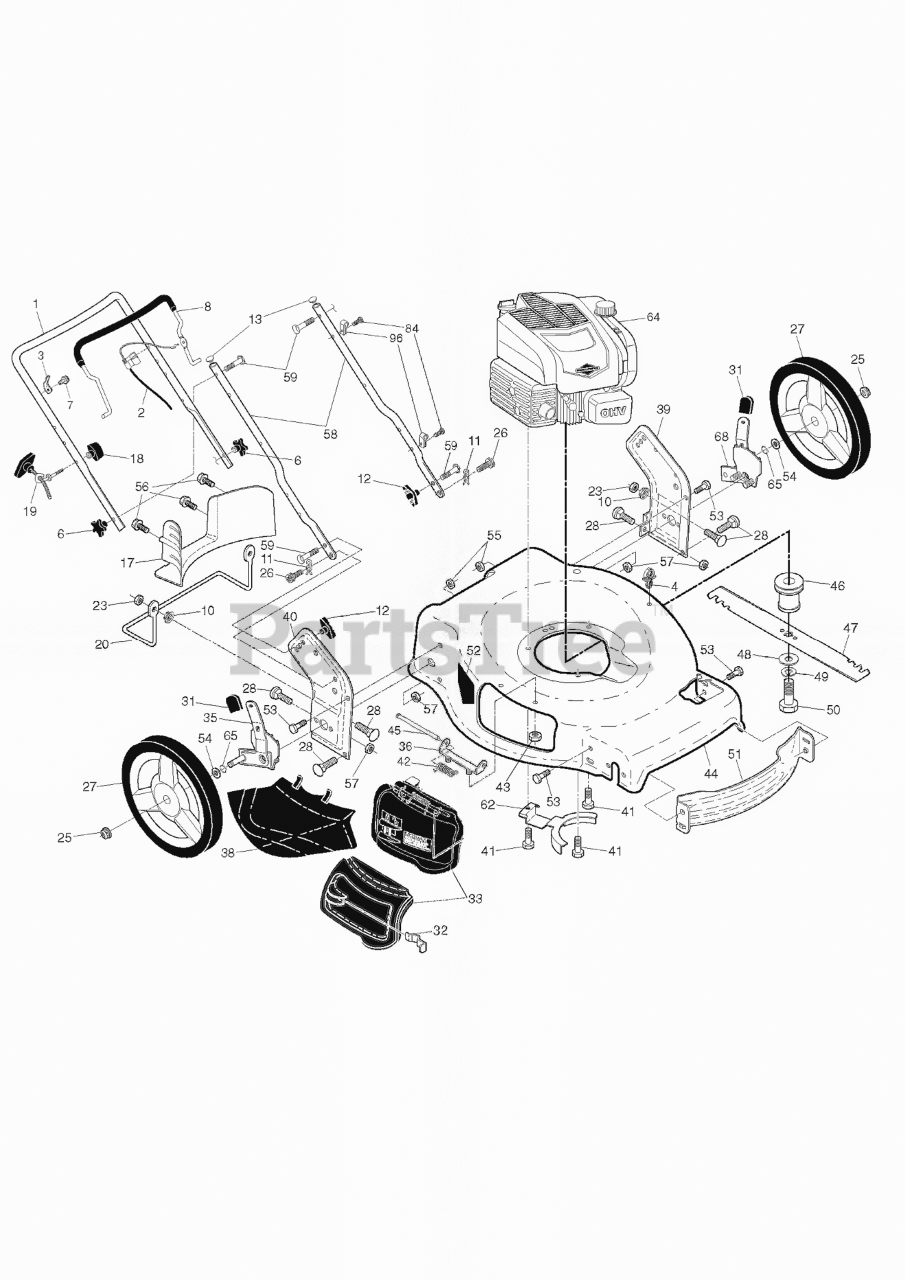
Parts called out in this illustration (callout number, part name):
1	HANDLE.UP.CURV.PUSH.498
2	CABLE.MZR.FGD.PLUS
2	CABLE.MZR.FGD.22+.ERGO
3	BRACKET.UPSTOP.RT
6	KNOB.HANDLE.PLASTIC.STAR.BLACK
7	SCREW
8	BAIL.OVER.MOLD.ERGO.MZR.ORANGE
8	BAIL.OM.ERGO.BENT.MZR.ORAN.668
10	WASHER 5/16"
11	COTTER.HAIRPIN.DOOR/HANDLE.PIV
12	KNOB, DEFLECTOR
13	PLUG.PLASTIC.7/8".14-20.GAUGE
17	BAFFLE.22PLUS.FGD.REAR.
18	T-KNOB.NEW ROPE GUIDE
19	GUIDE.ROPE.BLK.ZINC.CHROM
20	FOOTGUARD.REAR.22PLUS.BLK
23	LOCKNUT-FLANGE 5/16-18
25	NUT.HEX.FLANGE.3/8-16.LOCKNUT
26	SCREW,DOOR/HANDLE.PIVOT
27	WHEEL.12X1.75.CF H3SPK.RAD3.BB
28	BOLT
28	BOLT.CARRIAGE.LN.5/16-18X.5/8
31	SELECTOR KNOB
32	LATCH.DOOR.ZINC
33	DOOR ASSY KIT.MULCH DOOR.CE 22
33	DOOR.MULCH.22 PLUS.HUSQ.GREY
35	ADJUSTER.ASM.9POS.HW.R/R
36	BRACKET.ASM.HINGE.21.FWGD.
38	DEFLECTOR.CLIPPING.22.BLACK
39	BRACKET.ASM.HANDLE.LT.22+.GREY
39	BRACKET.ASM.HNDL.LT.22+.GREY
40	BRACKET.ASM.HNDL.RT.22+.GREY
40	BRACKET.ASM.HANDLE.RT.22+.GREY
41	BOLT 3/8-16X1-1/8
42	SPRING.TORSION
43	NUT.FLANGE.1-4-20-SERR
43	NUT.HEX.FLANGE.1/4
44	KIT.HSG.22+FGD.SIDE.668.CE
45	ROD.HINGE.21
46	ADAPTOR BLADE 25MM STAR
46	ADAPTER.BLADE.25M.22+FGD.2PIN
47	BLADE.22+4N1.2PIN.5STAR.(P07)
48	WASHER,HARDEN
49	LOCKWASHER
50	SCREW, HEX HD 3/8-24 X 1-3/8
51	BAFFLE.FRONT.22.PLUS
52	DECAL.INTERNATIONL.CUTFINGER
53	BOLT.5/16HEX.WHS.HD
54	WASHER.FLAT.1/2
55	NUT.HEX.FLANGE.1/4
56	SCREW.HX.13X.750
57	NUT.FLANGE.5/16
58	HANDLE.LOWER.22+BT.2PC.GRY
58	HANDLE.LOWER.22+.BT.GRAY
59	BOLT, HANDLE 5/16-18X1.75
62	BRACKET.ENG/BELTKEEPER
65	O-RING..070X.487.NEOPRENE
68	ADJUSTER.ASM.9POS.HW.R/L
84	FASTENER.PUSH.O.250X0.783
96	CLIP.CABLE.BLK
